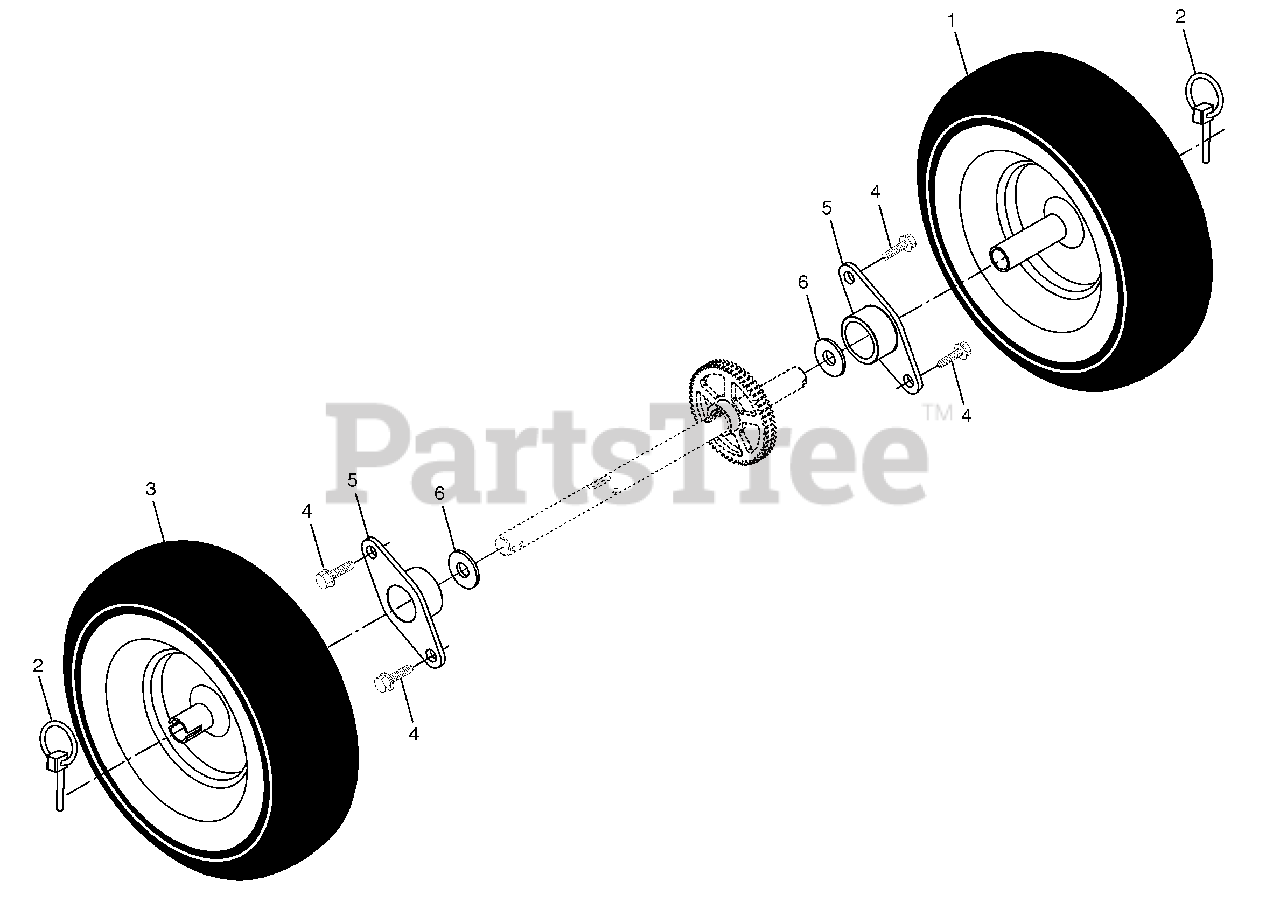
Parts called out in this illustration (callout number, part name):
1	Wheel Assembly, 16", LH
2	Pin, Klik 1/4
3	Wheel Assembly, 16", RH
4	Screw, Hex Head 5/16-18 x 5/8
5	Bearing, Axle
6	Washer, Thrust (1")
